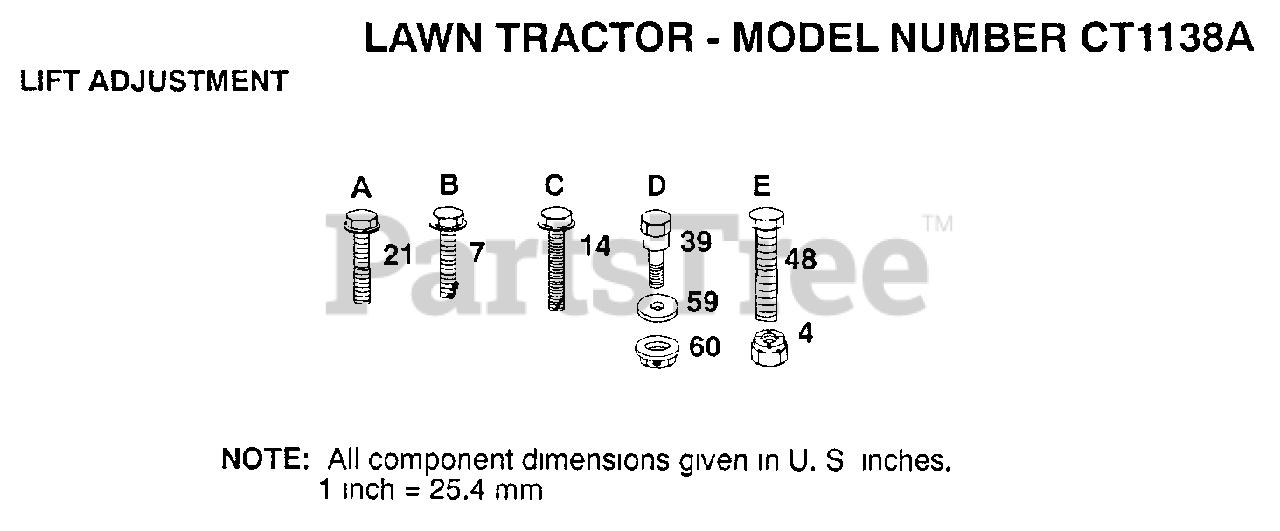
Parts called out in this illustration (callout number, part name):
7	SCREW
14	SCREW
21	SCREW LT
39	"BOLT, SHOULDER LT"
59	WASHER T
60	NUT SPECIAL T
